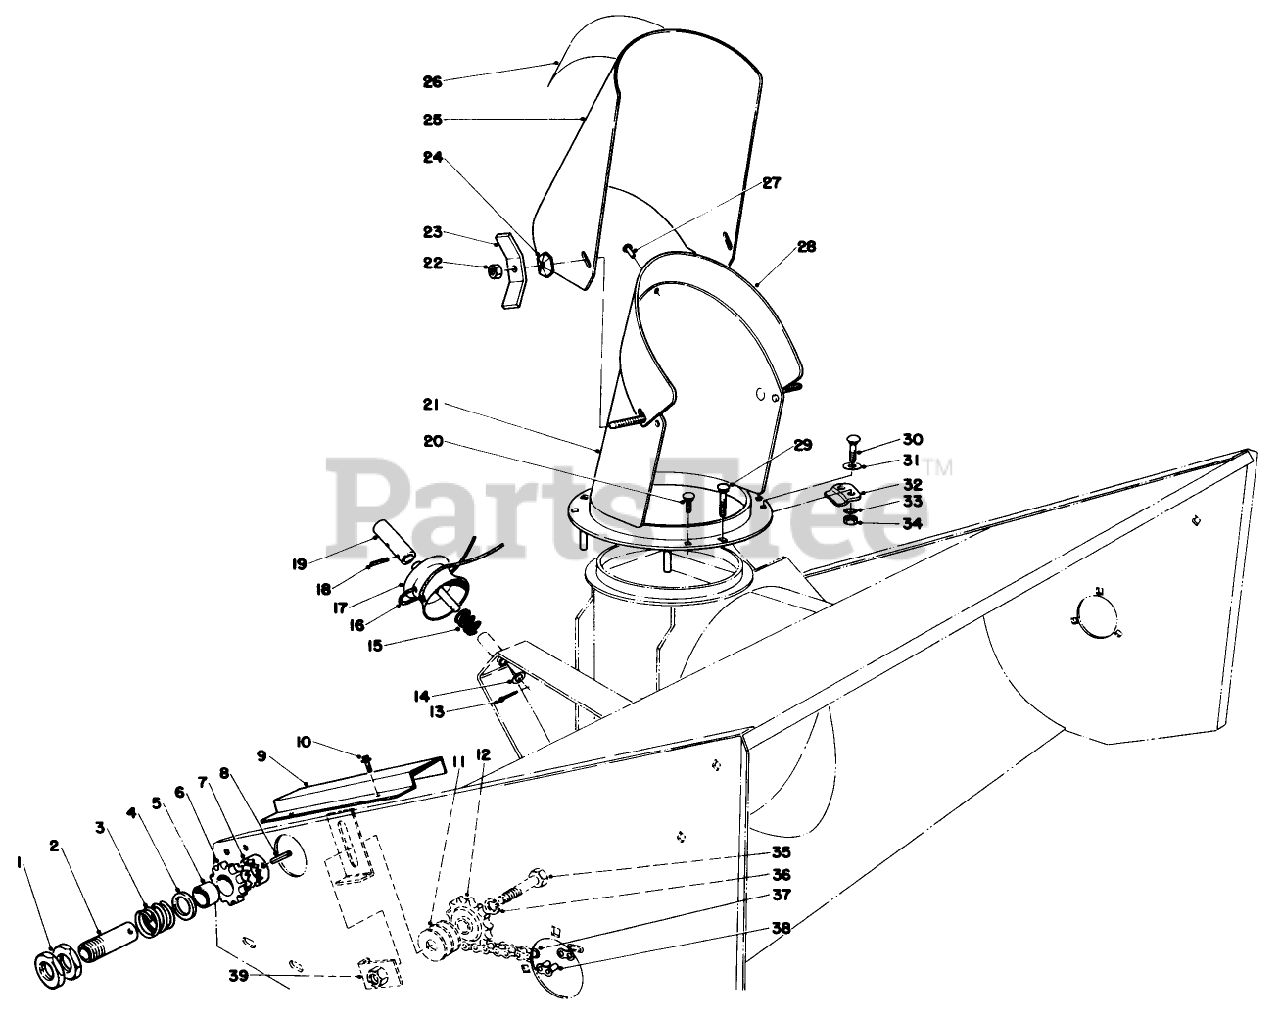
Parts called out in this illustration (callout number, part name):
1	THIN NUT
2	Clutch Sleeve
3	COMP SPRING
4	SPACER ECK PRES
5	BUSHING
6	Clutch Sprocket
7	Clutch Collar
8	ROLL PIN
9	Chain Cover
10	SCREW-HWHTF
11	WASHER-FLAT
12	IDLER SPRKT (60016)
13	PIN-COTTER
14	WASHER-FLAT
15	Spring-Compression
16	Cable
17	Pulley
18	PIN-SPRING
19	Tube-Connector
20	SCREW-CARR
21	Spout
22	NUT-LOCK, NI
23	Wing Nut
24	WASHER-LOCK
25	Deflector
26	Decal-Warning
27	.125 X 1/8 POP RIVET
28	Seal-Plastic
29	SCREW-CARR
30	BOLT-CARR
31	WASHER-FLAT
32	Clamp-Spout
33	WASHER-LOCK
34	NUT-HEX
35	SCREW-HH
36	WASHER-LOCK
37	ROLLER CHAIN (60023)
38	LINK-CHAIN
39	NUT PLATE WA (60095)
